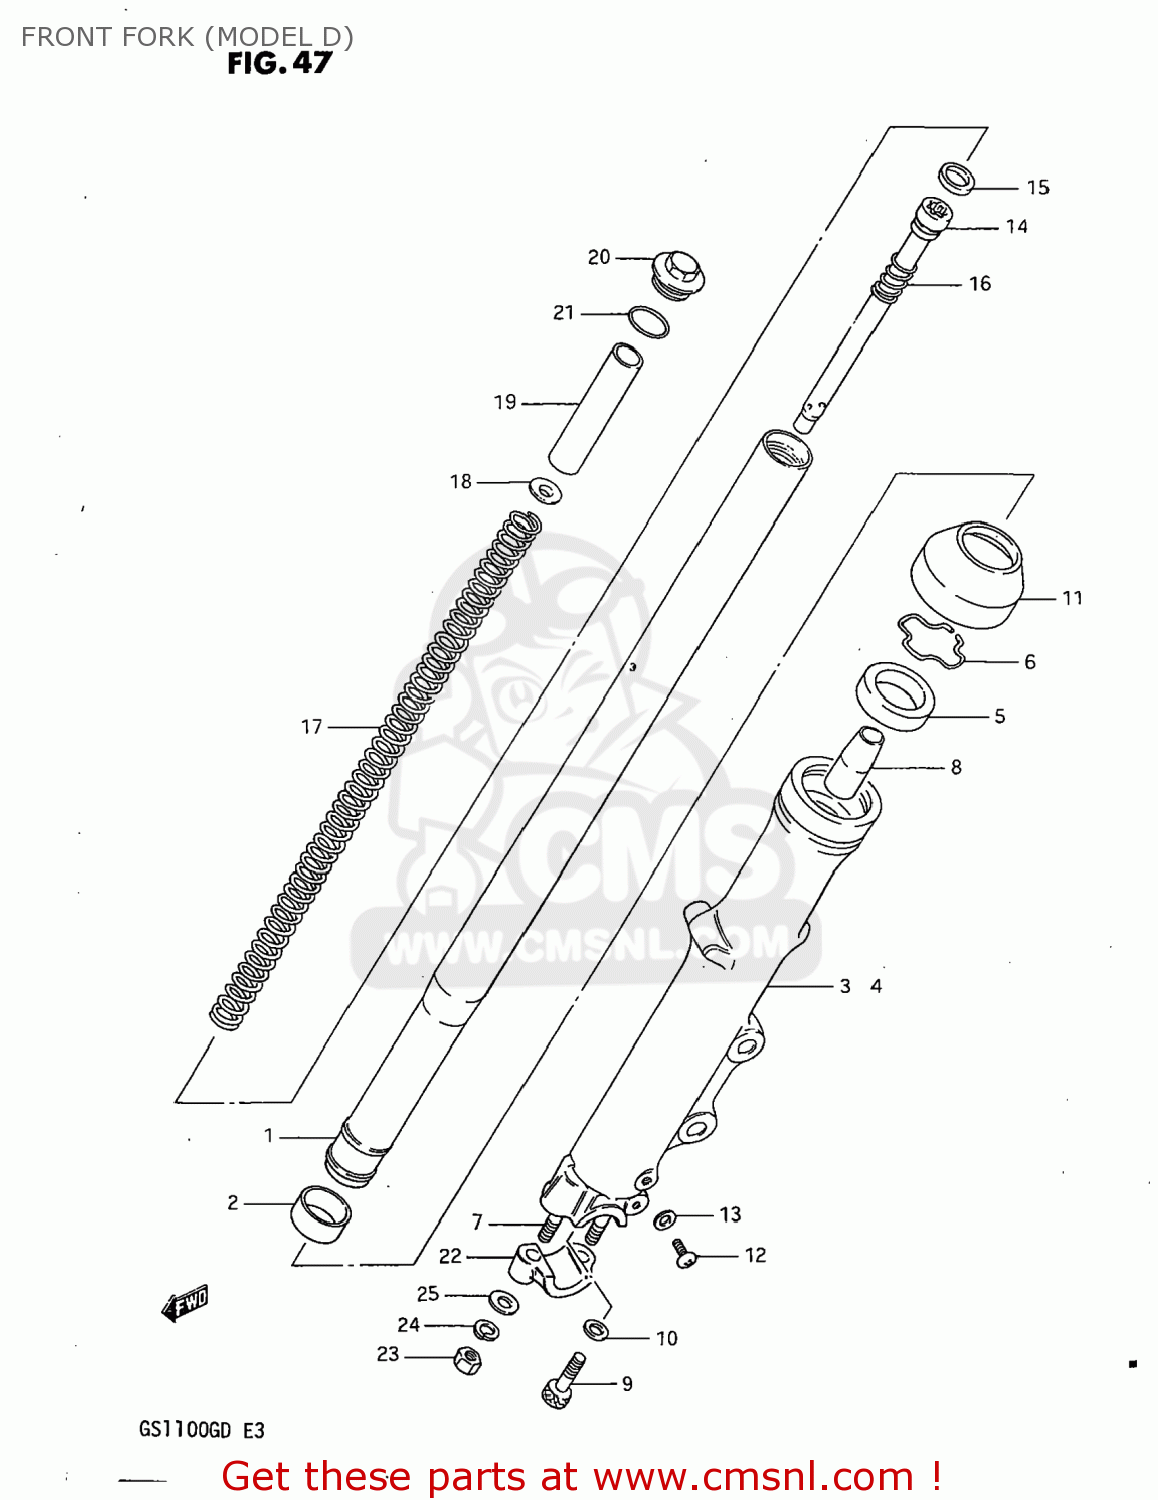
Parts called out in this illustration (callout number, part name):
1	TUBE,FORK,INNER
2	PISTON
3	TUBE,FORK,OUTER,RIGHT
4	TUBE,FORK,LEFT,OUTER
5	OIL SEAL,FRONT FORK
6	RING,STOPPER
7	STUD 8X30
8	PIECE,OIL LOCK
9	BOLT,FORK CYLINDER(10X25)
10	GASKET (NAS)
11	SEAL,DUST
12	SCREW
13	GASKET,DRAIN,PLUG (NAS)
14	CYLINDER,FRONT FORK
15	RING,PISTON
16	SPRING,REBOUND
17	SPRING,FRONT FORK
18	GUIDE,FRONT FORK SPRING C
19	SPACER,SPRING
20	CAP,FORK INNER TUBE
21	O RING
22	HOLDER,AXLE
23	NUT (8MM)
24	LOCK WASHER
25	WASHER
